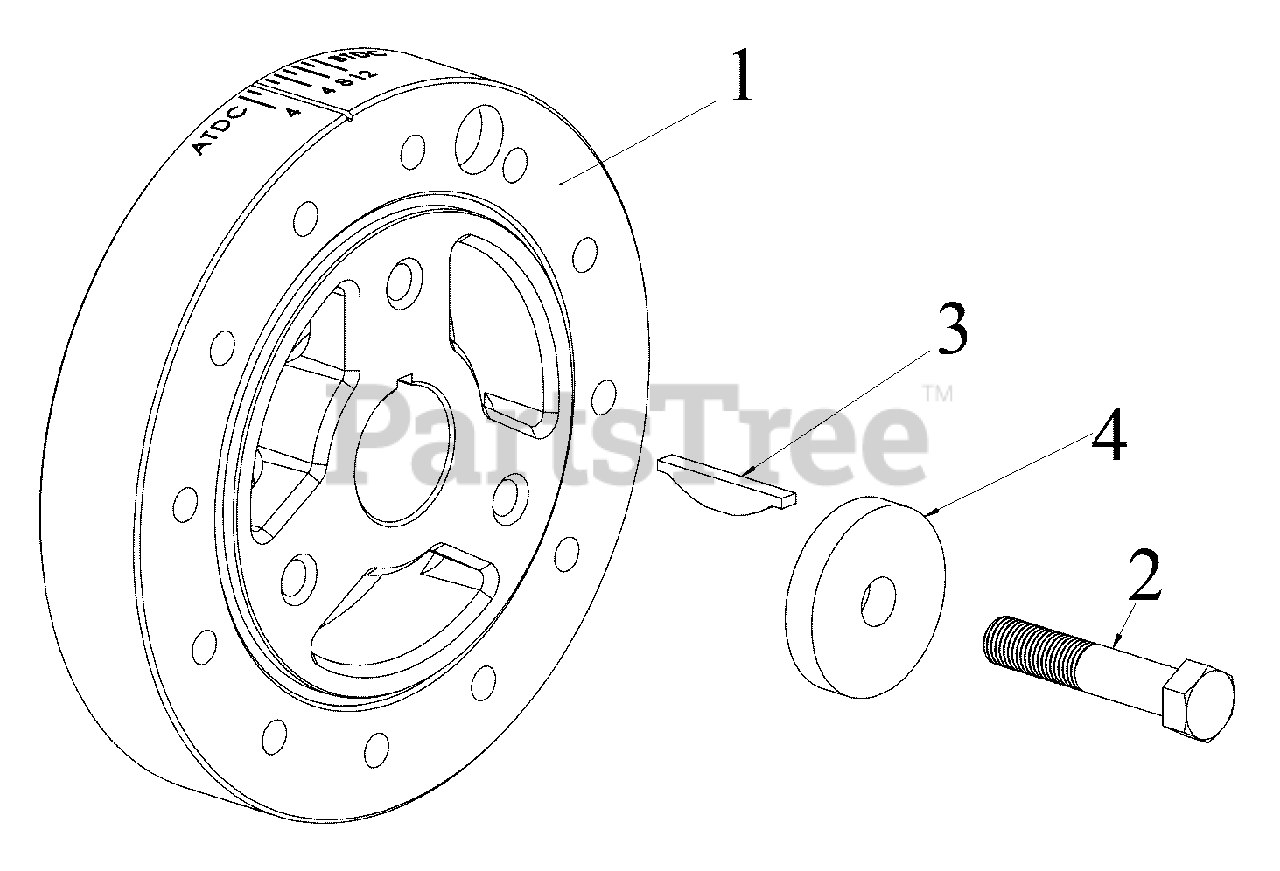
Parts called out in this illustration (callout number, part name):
1	DAMPER
2	BOLT, DAMPER
3	KEY, CRANKSHAFT
4	WASHER
